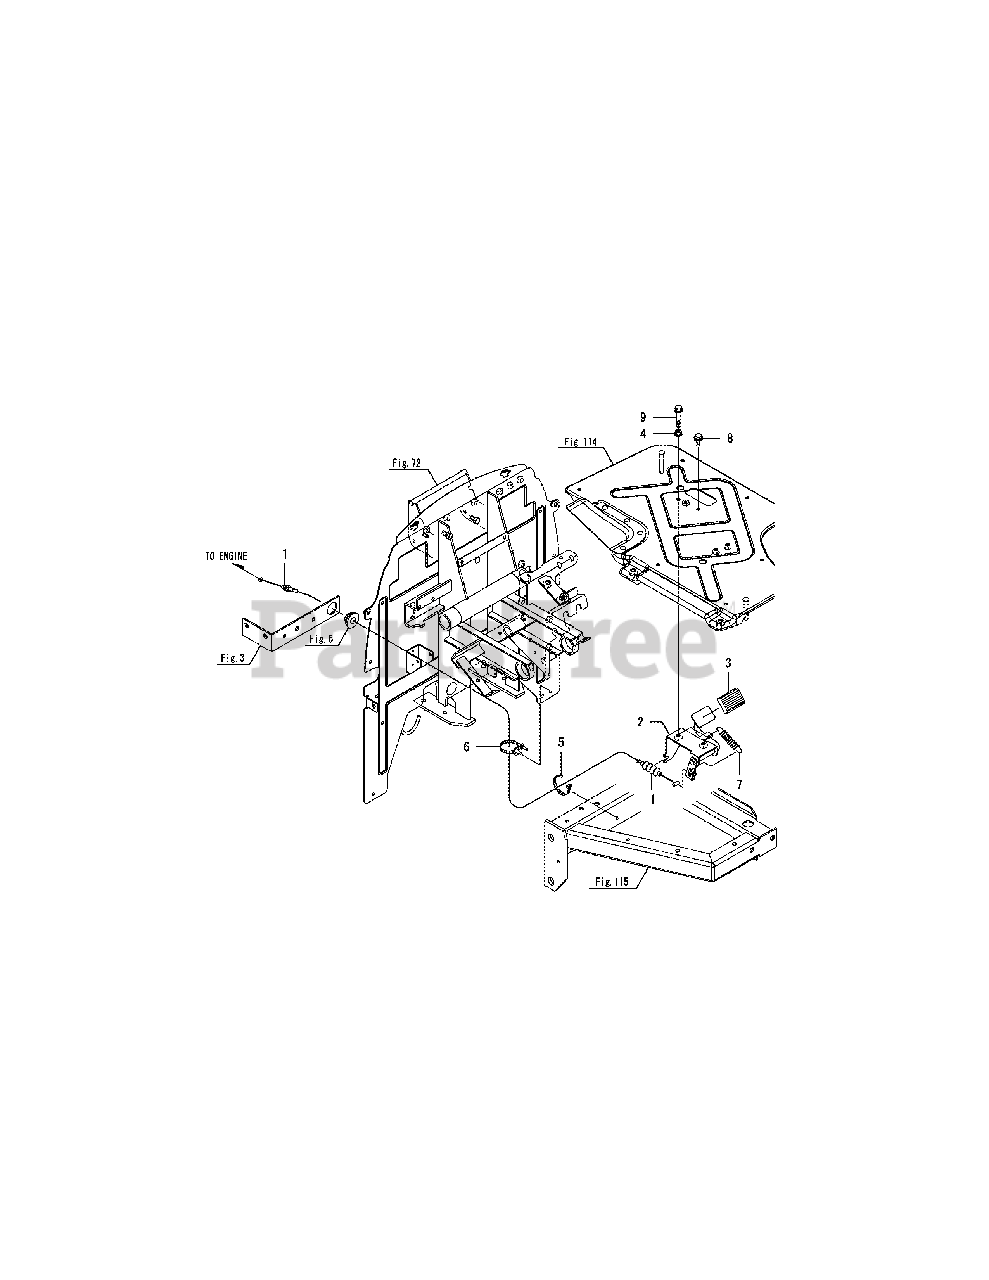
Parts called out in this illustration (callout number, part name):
1	CABLE, CONTROLE
2	CONTROL UNIT, FOOT
4	NUT W/WASHER 6
8	BOLT M 6X 12 PLATED
9	BOLT M 6X 40 PLATED
